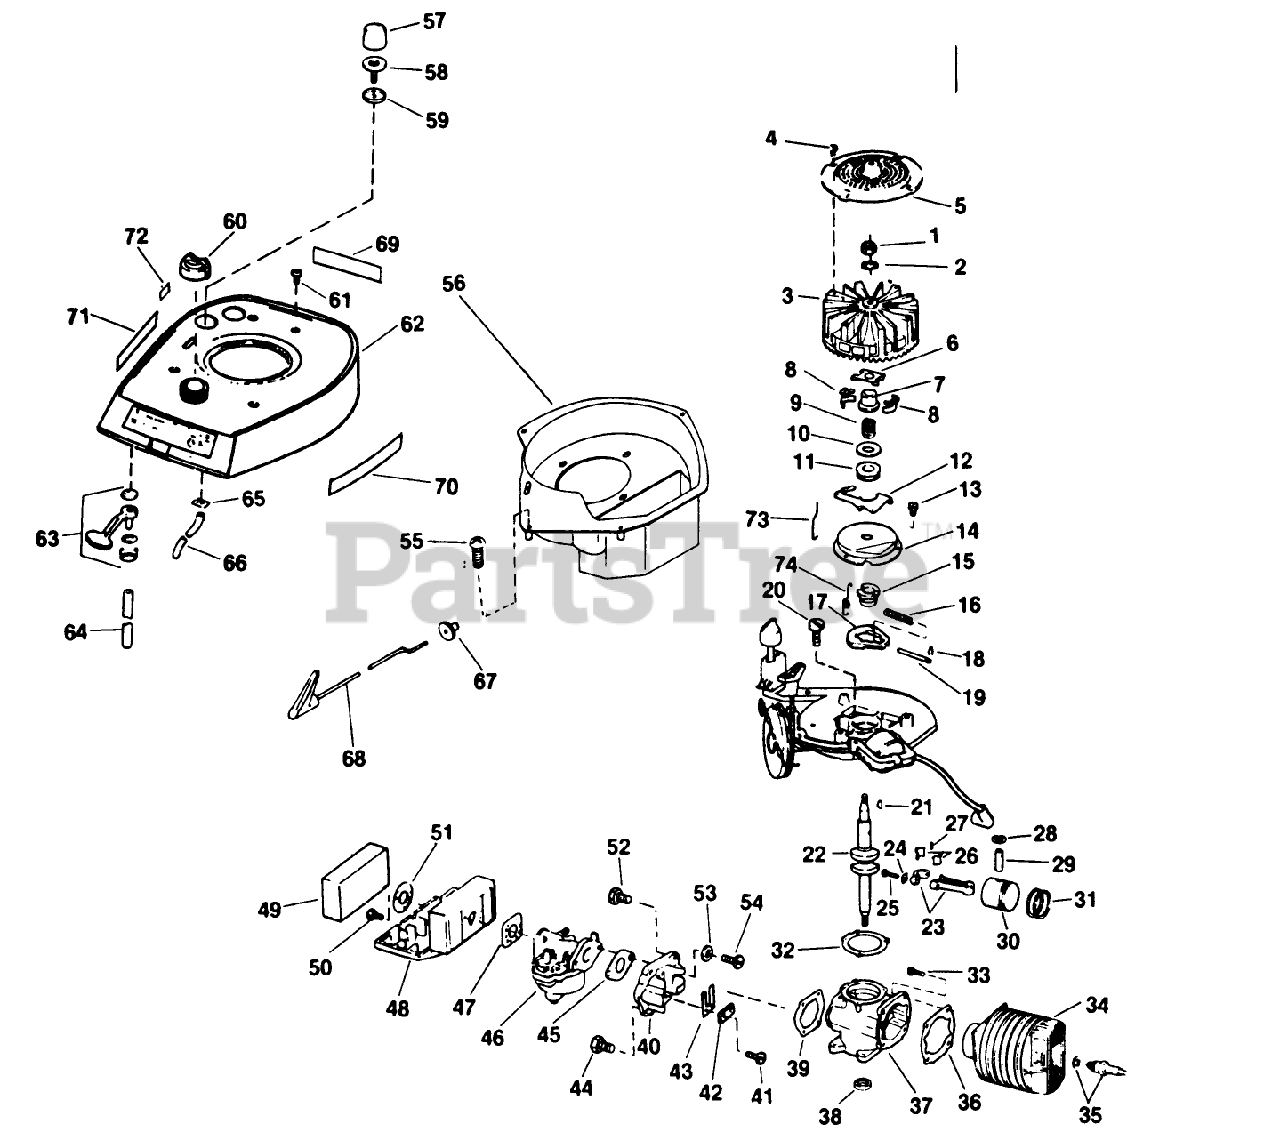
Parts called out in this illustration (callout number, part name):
1	NUT
3	Flywheel Screen Assy.
4	SCREW F
5	FLYWHEEL SCREEN
6	YOKE S
7	COLLAR S
9	SPRING S
11	THRUST COLLAR S
12	LEVER-GOVERNOR S
13	SCREW S
14	DUST COVER S
15	SPARK ADV. S
16	SPARK ADV. SPRING S
17	FLYWEIGHT S
18	SPARK ADJ. SPRING
19	PIN,SPARK ADV. S
21	KEY
25	SCREW
26	LINER ASM
28	RING-RETAINING
32	GASKET S
35	Spark Plug and Gasket
36	GASKET S
39	GASKET S
40	REED PLATE AY. S
42	PLATE-BACKUP, REED
44	SCREW S
45	GASKET S
47	GASKET S
48	CASE
49	AIR FILTER S
50	SCREW S
51	WASHER S
52	SCREW S
59	CUP-BULB
61	SCREW S
64	GAS LINE
65	5239 19 DELUXE MOWEREV2
67	GROMMET
68	KNOB & ROD AY. S
73	ROD S
74	SPRING
